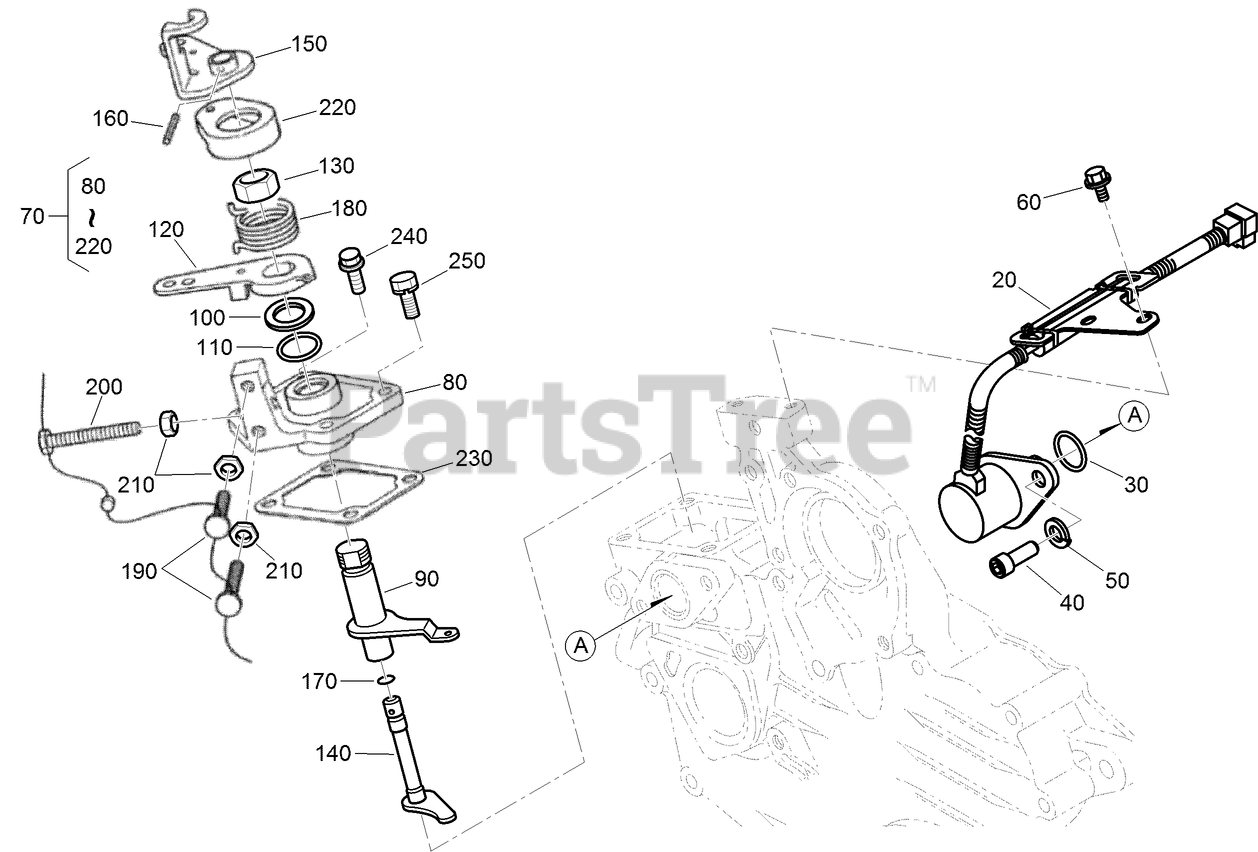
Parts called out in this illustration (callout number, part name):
20	SOLENOID STOP ASM
30	O-RING
40	BOLT-HSH
50	WASHER-SPRING
60	BOLT-FLANGE
70	SPEED CONTROL PLATE ASM
80	PLATE-CONTROL, SPEED
90	LEVER-GOVERNOR
100	COLLAR
110	O-RING
120	LEVER-CONTROL, SPEED
130	NUT-CONTROL, SPEED
140	SHAFT-LEVER
150	LEVER-STOP, ENGINE
160	PIN-SPRING
170	O-RING
180	SPRING-RETURN
190	SCREW-STOPPER
230	GASKET-PLATE, CONTROL
240	BOLT-FLANGE
